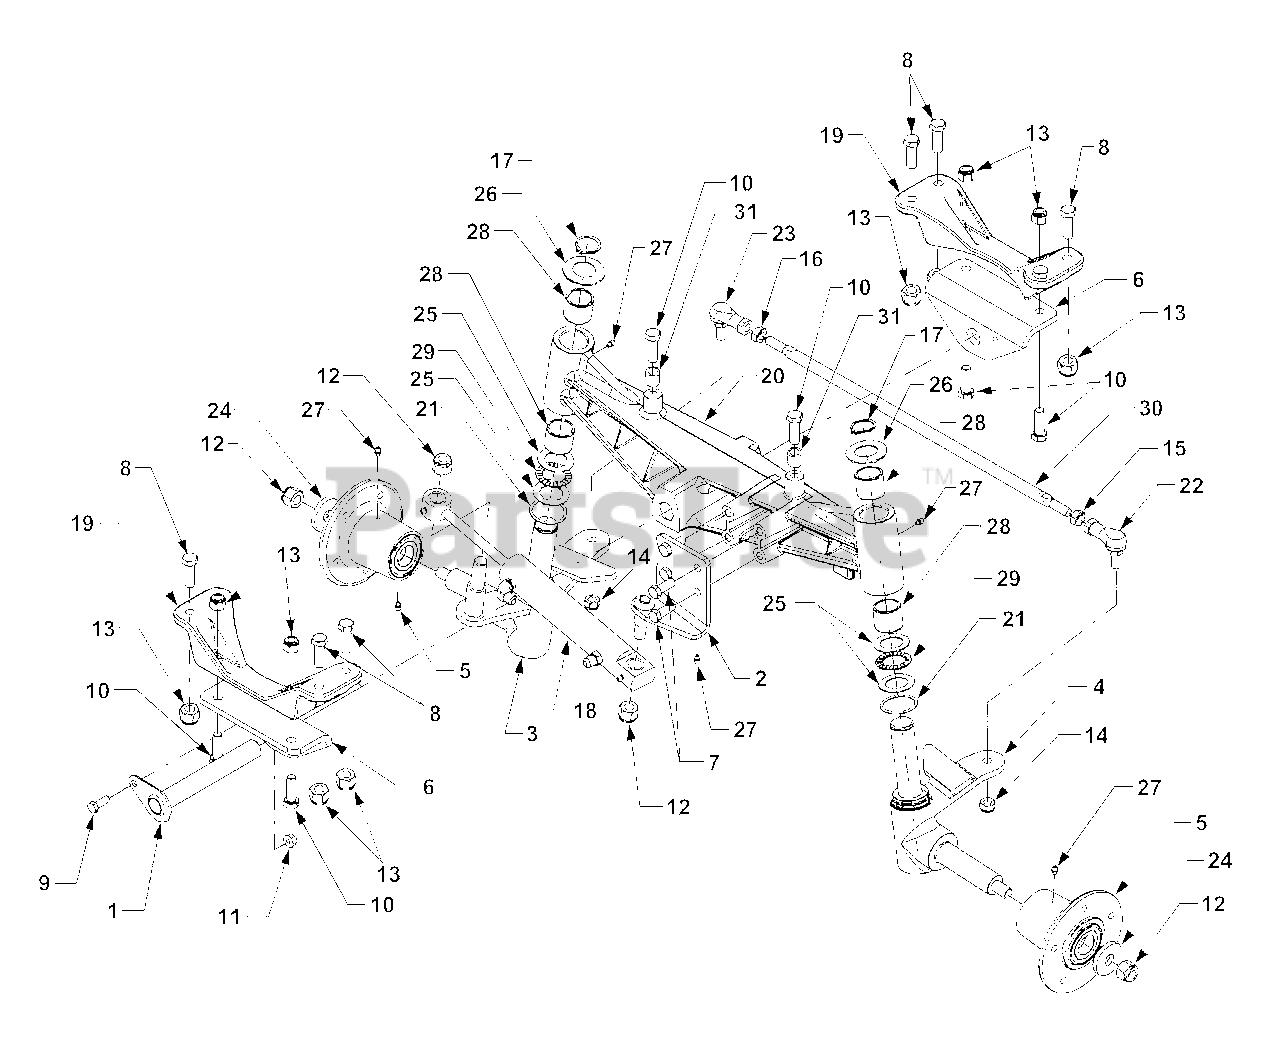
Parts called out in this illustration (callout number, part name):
1	Pin, Pivot Axle
2	Plate, Steering Cylinder Mtg.
3	Spindle Assembly, Steering LH
4	Spindle Assembly, Steering RH
5	Hub Assembly
6	Plate, Pivot Axle Mtg.
7	Screw, Hex Cap, M12-1.75 x 25 GR8
8	Screw, Hex Cap, 1/2-13 x 1.75 GR5
9	Screw, Hex Cap 3/8-16 x 1.0 GR5
10	Screw, Hex Cap 1/2-13 x 1.5 GR5
11	Nut, Hex Flange Lock, 3/8-16 GR5
12	Nut, Hex Insert Lock 5/8-11 GR5
13	Nut, Hex Insert Lock, 1/2-13 GR8
14	Nut, Hex Flange Lock, M12 x1.75
15	Nut, Hex, M12 x 1.75 RH Thrd
16	Nut, Hex, M12 x 1.75 LH Thrd
17	Ring, Snap, 1.25 Dia Shaft
18	Cylinder, Steering
19	Bracket, Axle Mtg.
20	Axle, Pivot
21	O-Ring, 1.374 x .139
22	Ball Joint, RH Thrd
23	Ball Joint, LH Thrd
24	Washer, Flat, .66 x 1.94 x .25
25	Washer, Flat, 1.25 x 1.94 x .063
26	Washer, Flat, 1.25 x 2.25 x .040
27	Fitting, Lube, 3/6 Drive
28	Bearing, Sleeve, 1.25x1.5x1.25
29	Bearing, Thrust, 1.25 x 1.94 x .78
31	Spacer, .501 x .75 x .78
